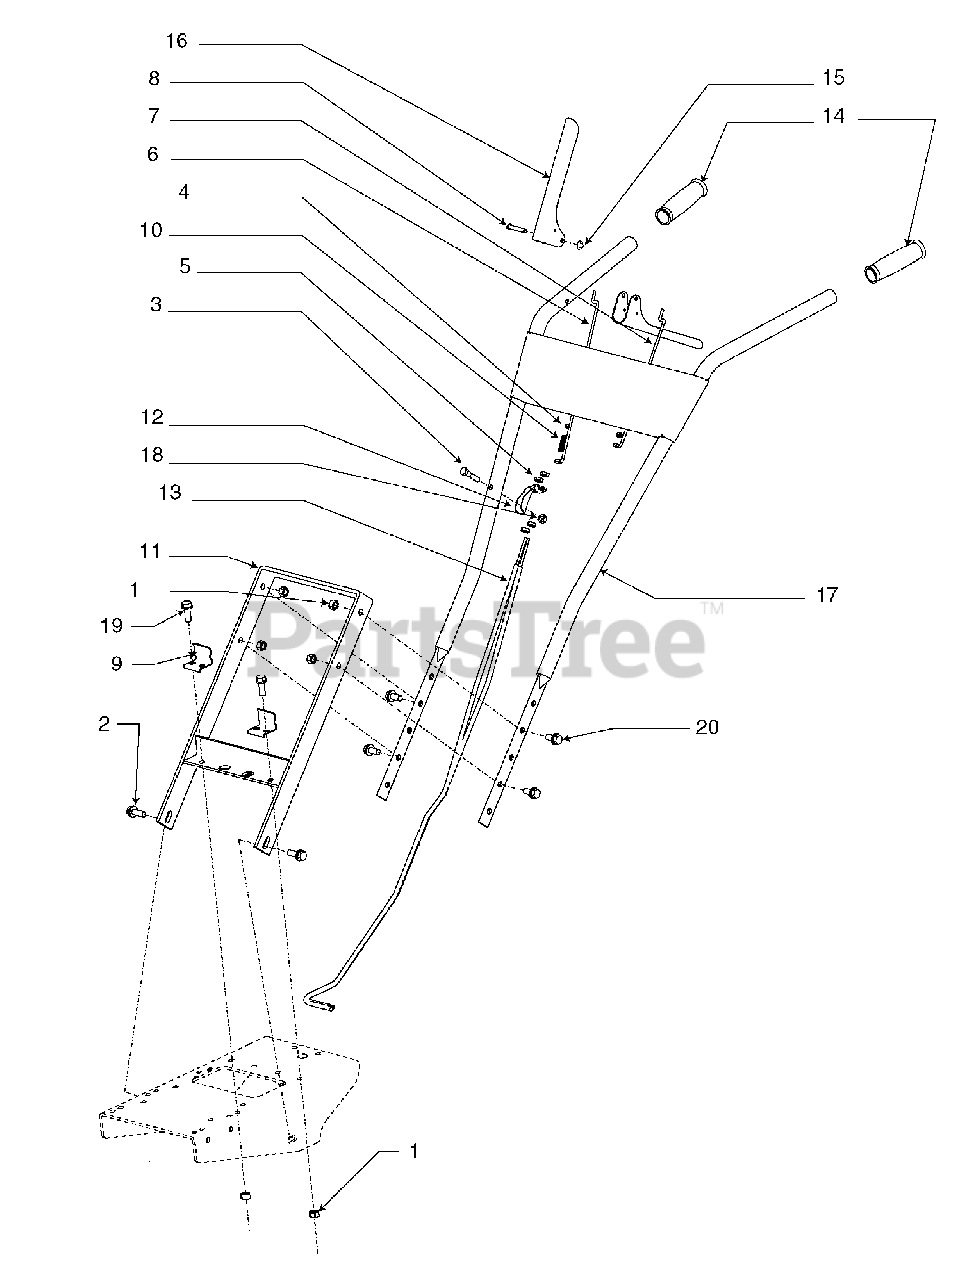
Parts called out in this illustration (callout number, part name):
1	NUT, Hex, Locking, Two-Way, 3/8-16
2	BOLT, Carriage, 3/8-16 x 1
3	BOLT, Hex-Head, 5/16-18 x 1
4	NUT, Hex, Ny-Lock, 10-24
5	NUT, Hex-Jam, 5/16-24
6	LINK, 11-5/8
7	LINK, 9-1/2
8	PIN, Clevis, 1/4 x 1-1/2
9	CLIP, Belt-Guard
10	SPRING, Compression, Forward Arm
11	MOUNT, Handlebar Assembly
12	BRACKET, Cable Mount
13	CABLE, Rear Tine, 39" Sheath
14	GRIP, Handlebar, Flangeless, 1"
15	NUT, Push, 1/4
16	LEVER, Control, Rear Tine
17	HANDLEBAR ASSEMBLY
18	NUT, Bi-Way Lock, 5/16-18
19	BOLT, Serrated Flange, 3/8-16 x 1
20	BOLT, Serrated Flange, 3/8-16 x 3/4
